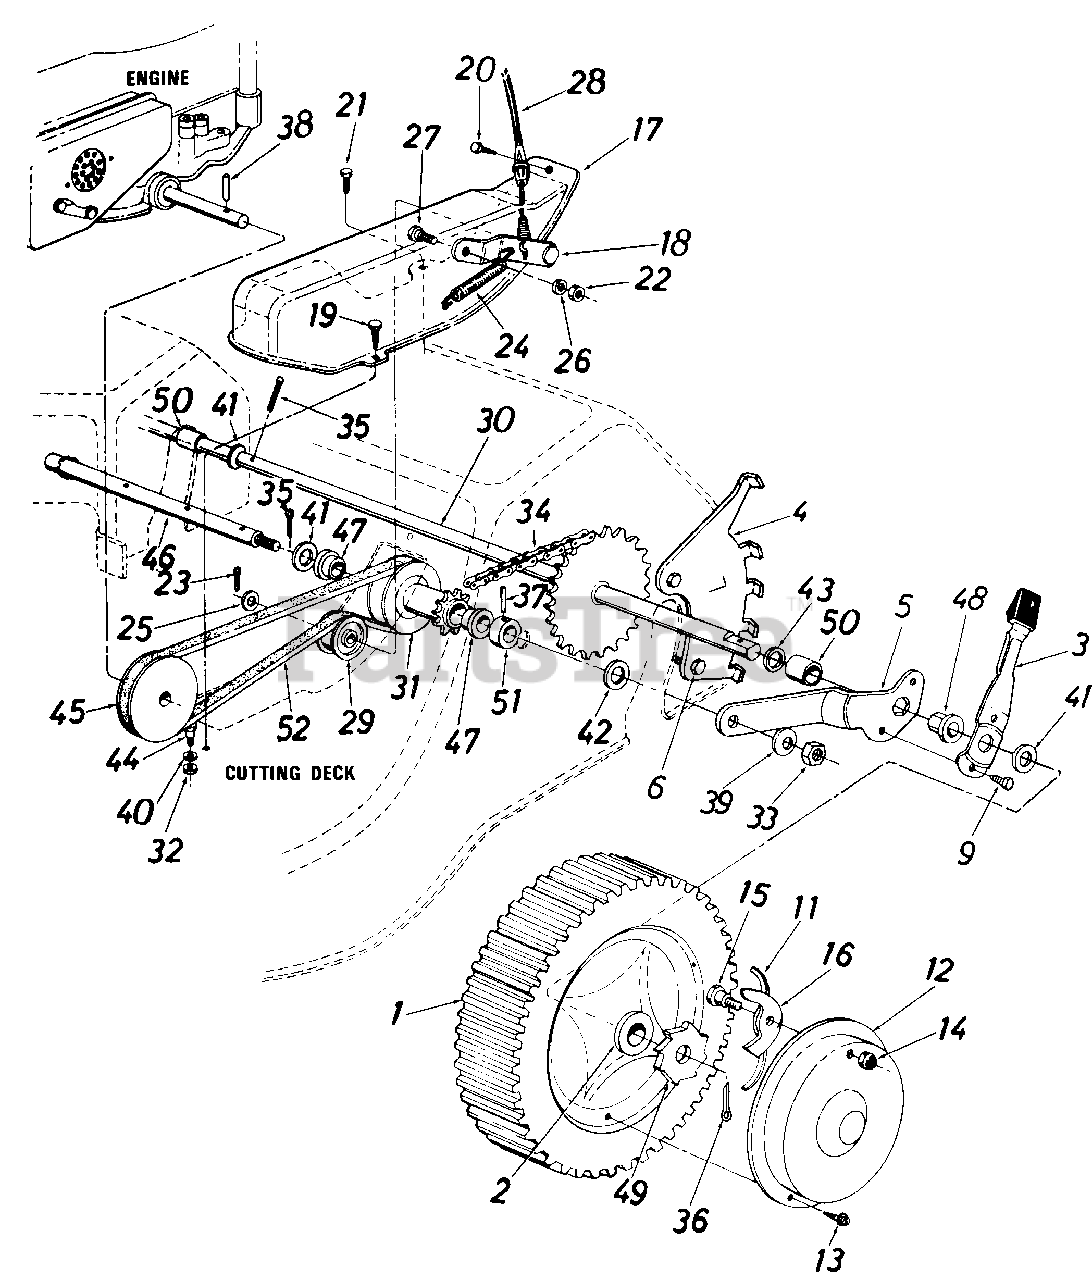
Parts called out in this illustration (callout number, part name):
1	Wheel Ass'y. Comp. 8.0 x 1 .75
2	Flange Brg.-1/2" I.D.
3	Spring Lever w/Knob
4	Index Plate-L.H.
5	Pivot Brkt.-L.H.
6	Hex Wash. Hd. Tap Scr 1/4 x .62" Lg.
9	Hex B-Tap Scr. 1/4 x .38" Lg.
11	Nylon Spring
12	Hub Cap
13	Pan Hd. Tap Scr. #12 x .50" Lg.
14	Hex Ins. L-Nut 1/4-20 Thd.
15	Shld. Bolt .342" Dia. x .268
16	Pawl
17	Belt Cover
18	Idler Bracket Ass'y.
19	Hex Wash. Hd. Self-Tap Scr. 1/4 -20 x .50" Lg.
20	Hex Drilling Scr. #10 x .50" Lg.
21	Hex TT-Tap Scr. 1/4-20 x .75" Lg.
22	Hex Nut 1/4-20 Thd.
23	Cotter Pin 1/8" Dia. x 1.00" Lg.*
24	Extension Spring .33" O.D. x 1.12" Lg.
25	Fl-Wash. .531" I.D. x .930" O.D.
26	L-Wash. 1/4" I.D.
27	Shld. Bolt .375" Dia. x .181
28	Clutch Cable-50"
29	Flat Idler-Plastic
30	Rear Shaft Ass'y.
31	Pulley w/9 Tooth Sprocket Ass'y.
32	Hex Nut 5/16-18 Thd.
33	Hex Jam Nut 3/8-16 Thd.
34	#48 Chain 1/2" Pitch x 31 Links
35	Cotter Pin 3/32" Dia. x 1.00" Lg.*
36	Cotter Pin 1/8" Dia. x 1.00" Lg.
37	Spring Pin Spir. 3/16" Dia. x 1.00" Lg.
38	Spring Pin Spir. 3/16" Dia. x 1.50" Lg.
39	Bell-Wash. .400" I.D. x .88" O.D.
40	L-Wash. 5/16" I.D.
41	Fl-Wash. .531" I.D. x .930" O.D.
42	Bell-Wash. .400" I.D. x 1.13" O.D.
43	Fl-Wash. .510" I.D. x 1.0" O.D.
44	Shld. Bolt .437" Dia. x .350" Lg.
45	Engine Pulley
46	Pulley Shaft-10.0" Lg.
47	Flange Brg. .506" I.D. Plastic
48	Hex Flange Brg. x .506" I.D. Plastic
49	Ratchet
50	Spacer .765" I.D. x .89" O.D. x.960" Lg.
51	Spacer .505" I.D. x .88" O.D. x.44" Lg.
52	"V"-Belt
